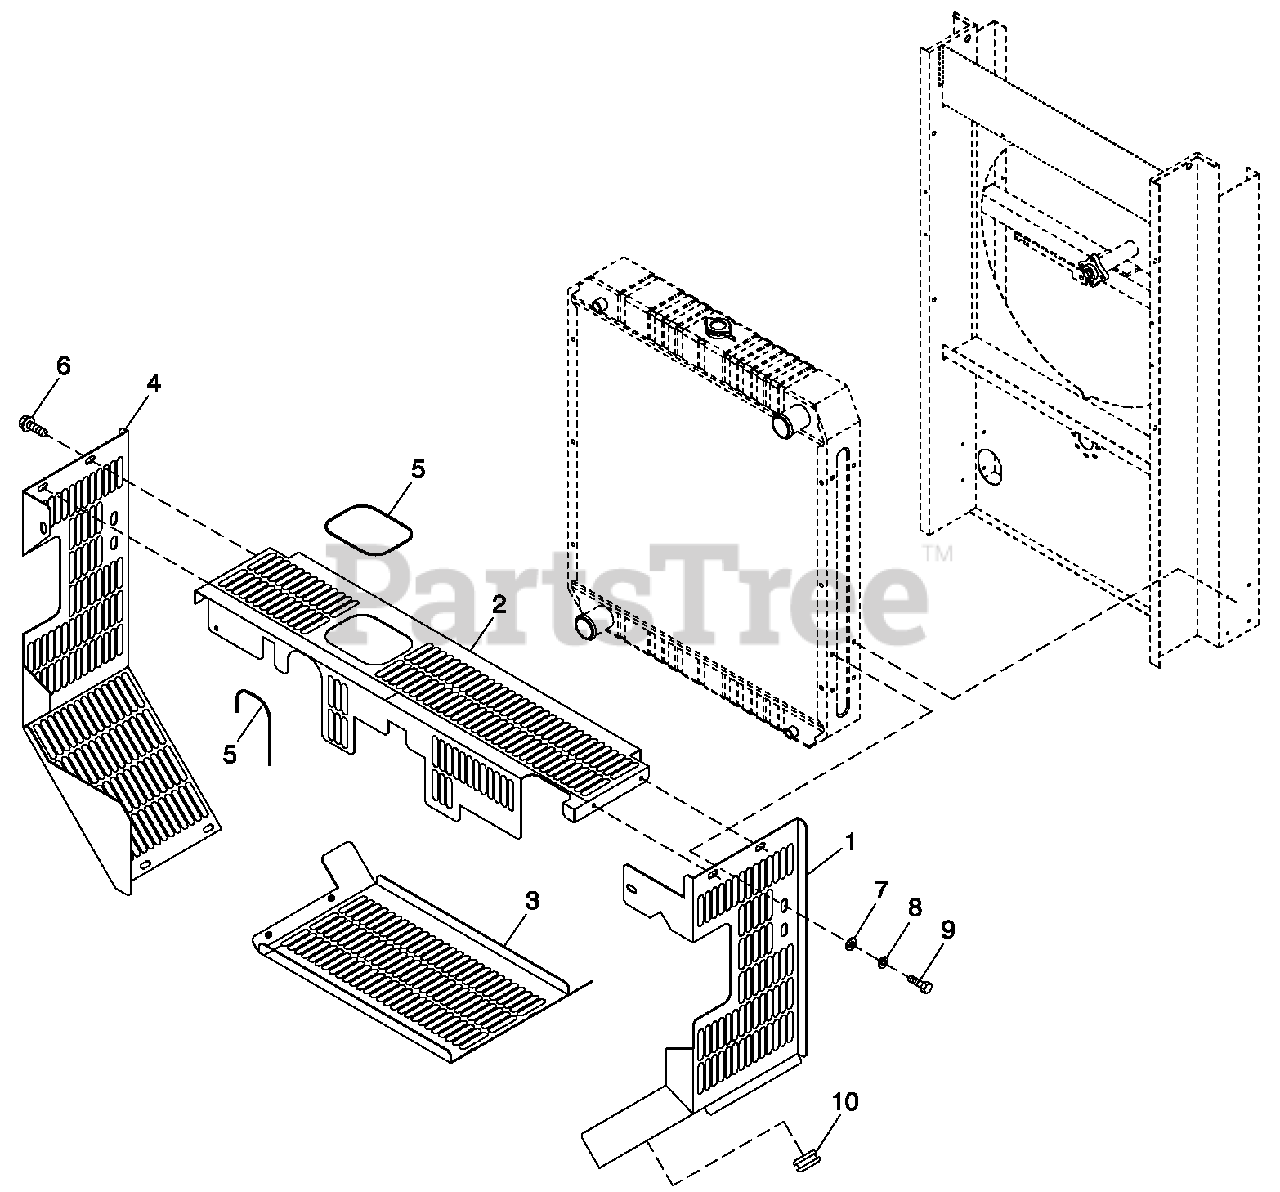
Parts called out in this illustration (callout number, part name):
1	GUARD BELT RIGHT HAND C5
2	GUARD BELT TOP C5
3	GUARD BELT BOTTOM C5
4	GUARD BELT LEFT HAND C5
5	TRIM VINYL BLACK 1/8GP
6	SCREW THF M6-1 X 16 N WA Z/JS
7	WASHER FLAT 3/8-M10 ZINC
8	WASHER LOCK M10
9	SCREW HHC M10-1.5 X 20 G8.8
10	GROMMET 1.25 X .25 X 1.00
